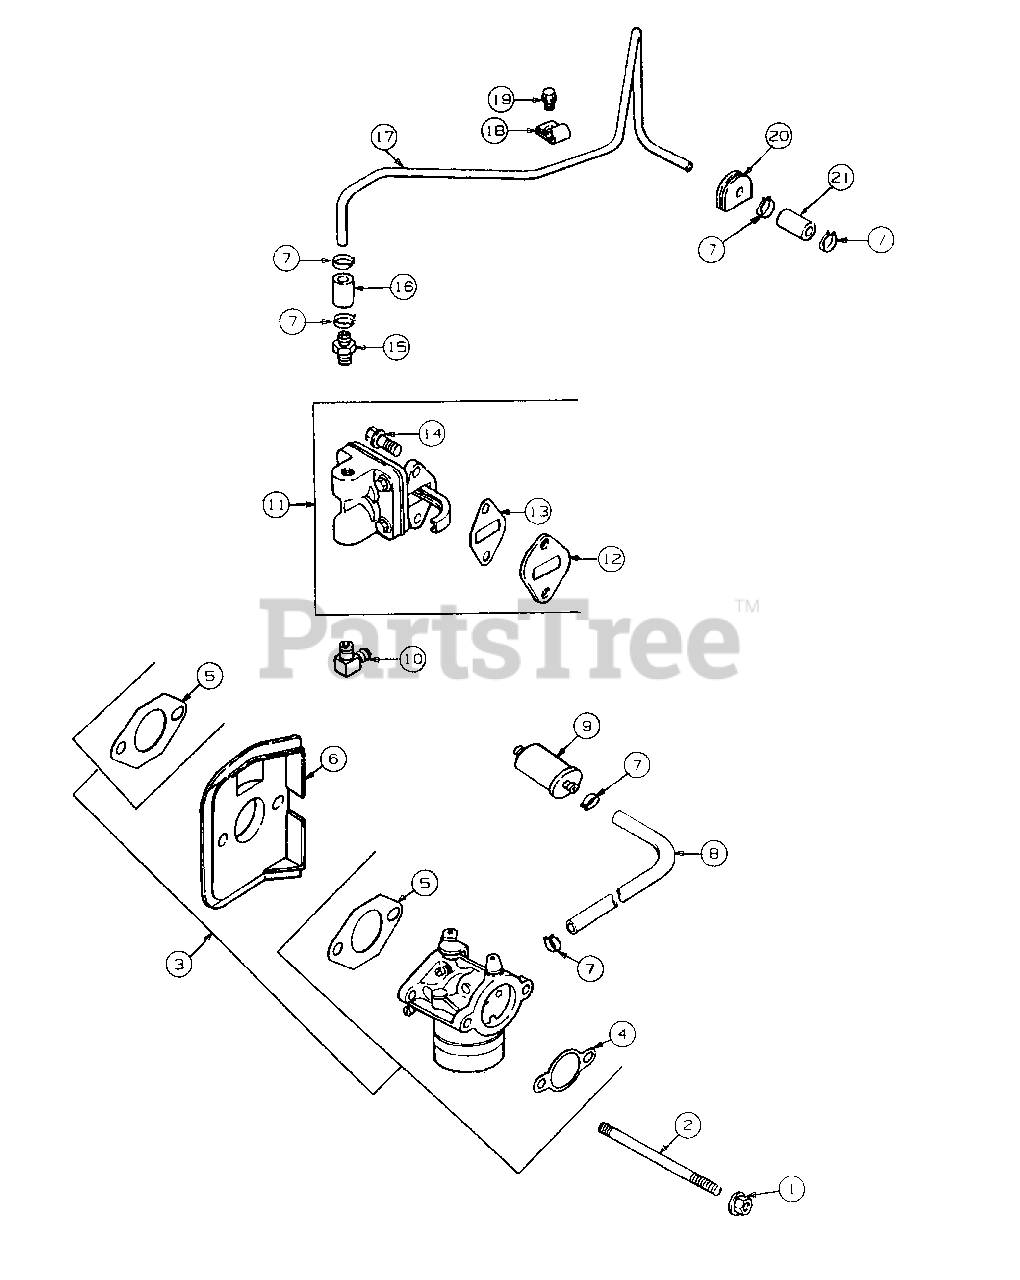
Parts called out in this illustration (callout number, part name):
1	Nut, Carburetor, M6 x 1.0
2	Stud, Carburetor, M6 X 1.0 X 110
3	Kit, Carburetor
4	Gasket, Air Cleaner
5	Gasket, Carburetor
6	Deflector, Heat
7	Clamp, Fuel Line
8	Line, Fuel, 3"
9	Filter, Fuel
10	Connector, 90°
11	Kit, Fuel Pump
12	Spacer, Fuel Pump
13	Gasket, Fuel Pump
14	Screw, Fuel Pump Mtg
15	Connector, Straight
16	Line, Fuel, 2-1/4"
18	Clamp, Fuel Line
19	Screw, Fuel Line Connecting
21	Line, Fuel, 1-1/4"
